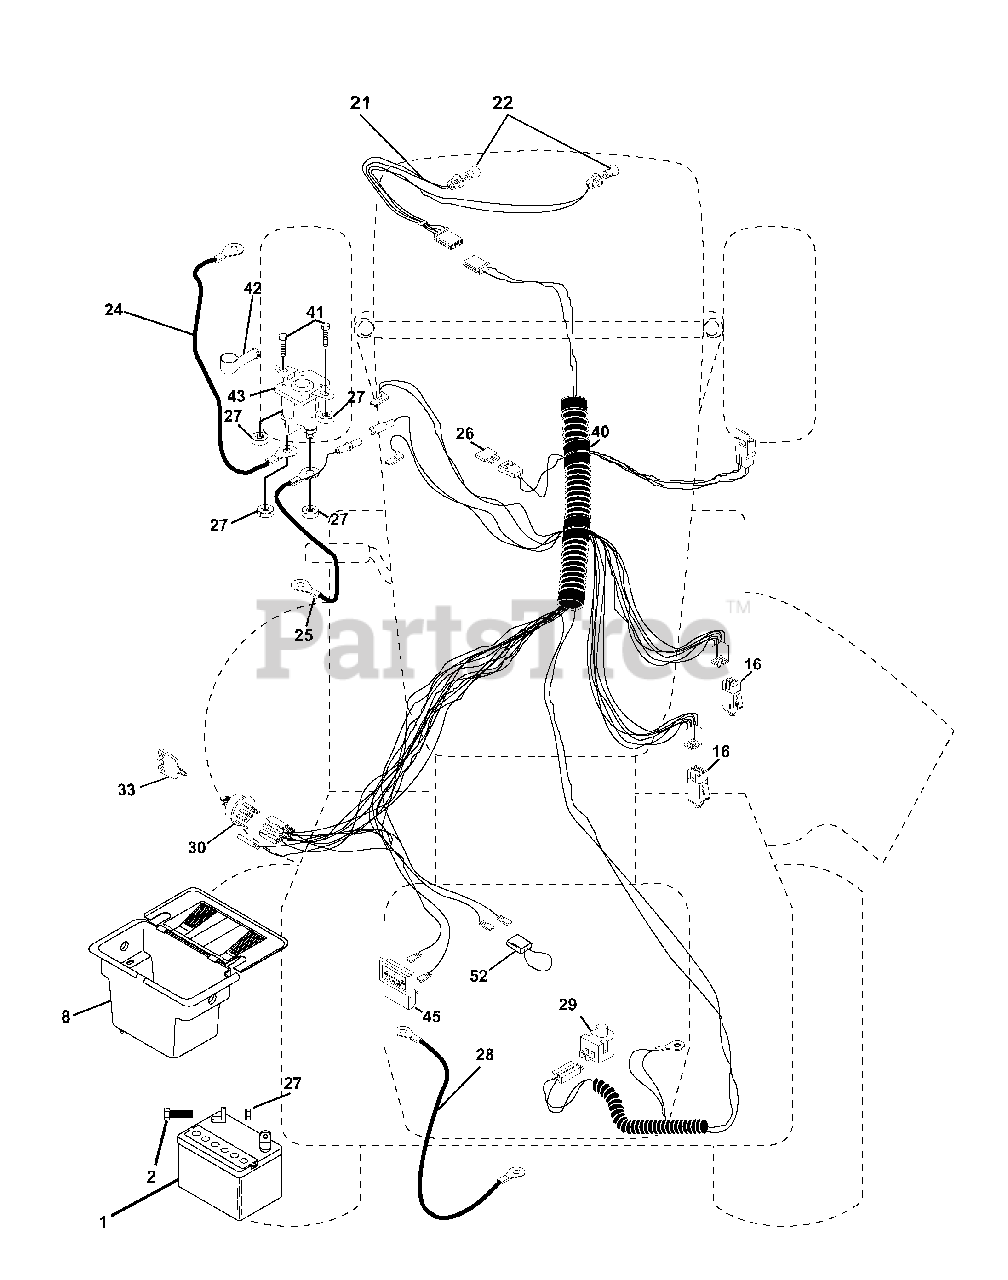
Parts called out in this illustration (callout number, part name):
1	Battery 12 Volt 25 Amp
2	Bolt Hex Hd 1/4-20unc X 3/4
8	Case Battery
16	Switch Interlock Push -In
21	Harness Asm Light W/4152J
22	Bulb Light #1156
24	Cable Battery 6 Ga 11" red
25	Cable Battery 6 Ga w/16 wire,red
26	Fuse 15 AMP
27	Nut Keps Hex 1/4-20 unc
28	Cable Ground 6 Ga 12" black
29	Switch Plunger Nc Gray
30	Switch Ign
33	Key Ign
40	Harness Ign
41	Bolt Blk Fin Hex 1/4-20 X 1/2
42	Cover Terminal Red
43	Solenoid
45	Ammeter
52	Protection Wire Loop
